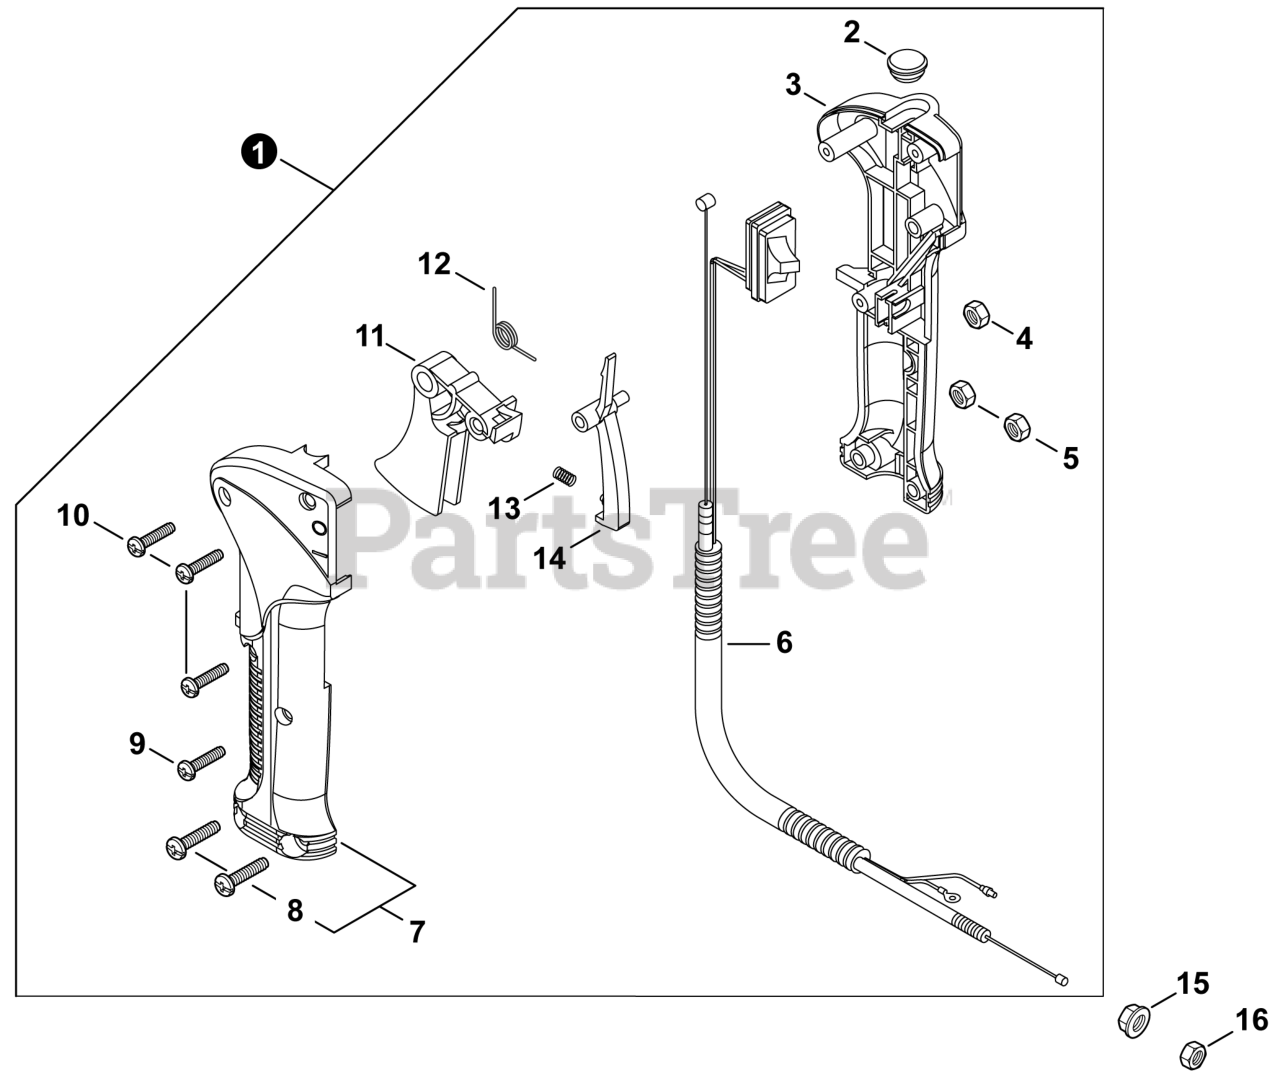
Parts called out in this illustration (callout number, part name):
1	THROTTLE CONTROL ASSY
2	PLUG, RUBBER
3	CONTROL HANDLE - RIGHT
6	CABLE ASSY, CONTROL
7	CONTROL HANDLE KIT
8	SCREW M5x22
9	SCREW M4x23
10	SCREW, TAPPING 4x16
11	TRIGGER, THROTTLE
12	SPRING, TORSION
13	SPRING, COMPRESSION
14	LOCKOUT, THROTTLE
15	NUT, FLANGE M6
